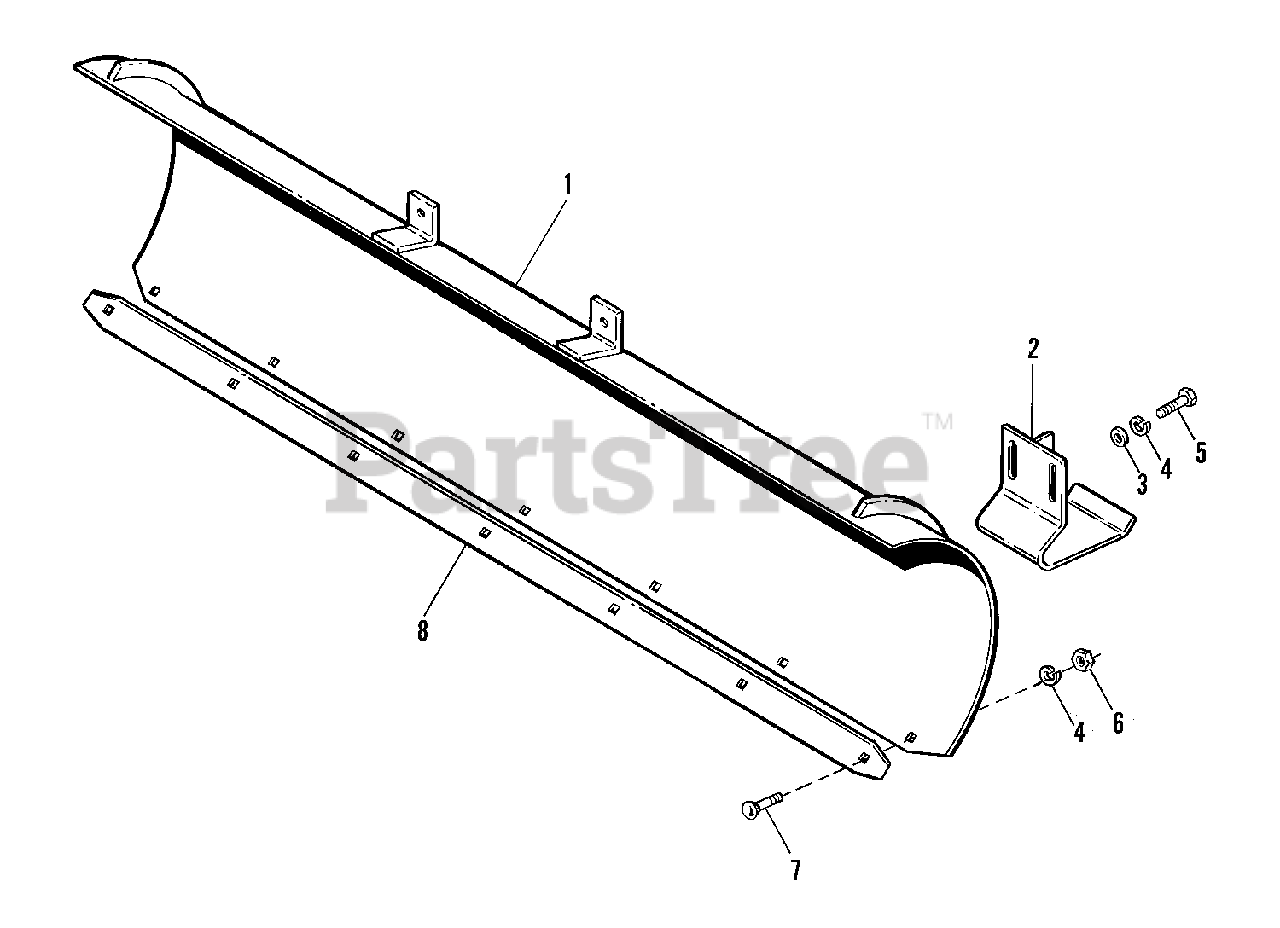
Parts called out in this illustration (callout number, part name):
1	BLADE ASSEMBLY, 60"
2	SHOE ASSEMBLY
3	WASHER, 3/8
4	WASHER, Lock, 3/8
5	CAPSCREW, Hex Head, 3/8-16 x 3/4
6	NUT, Hex, 3/8-16
7	CARRIAGE BOLT, 3/8-16 x 1
8	PLATE, Wear
